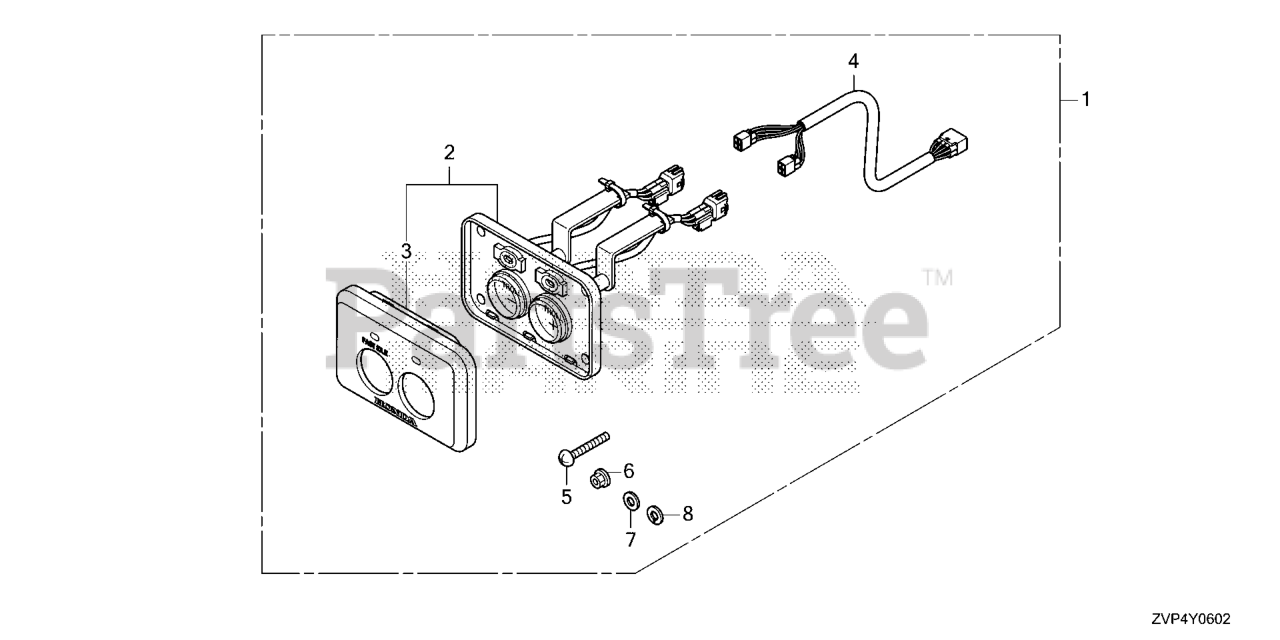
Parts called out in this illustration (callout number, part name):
1	PANEL KIT
2	PANEL ASSY., FUNCTION SWITCH
3	PANEL, FUNCTION SWITCH
4	SUB-HARNESS ASSY., FUNCTION SWITCH
5	SCREW, PAN (5X40) DUAL QTY = (8) (SINGLE)
6	NUT, FLANGE (5MM)
7	WASHER, PLAIN (5MM)
8	WASHER, SPG (5MM)
